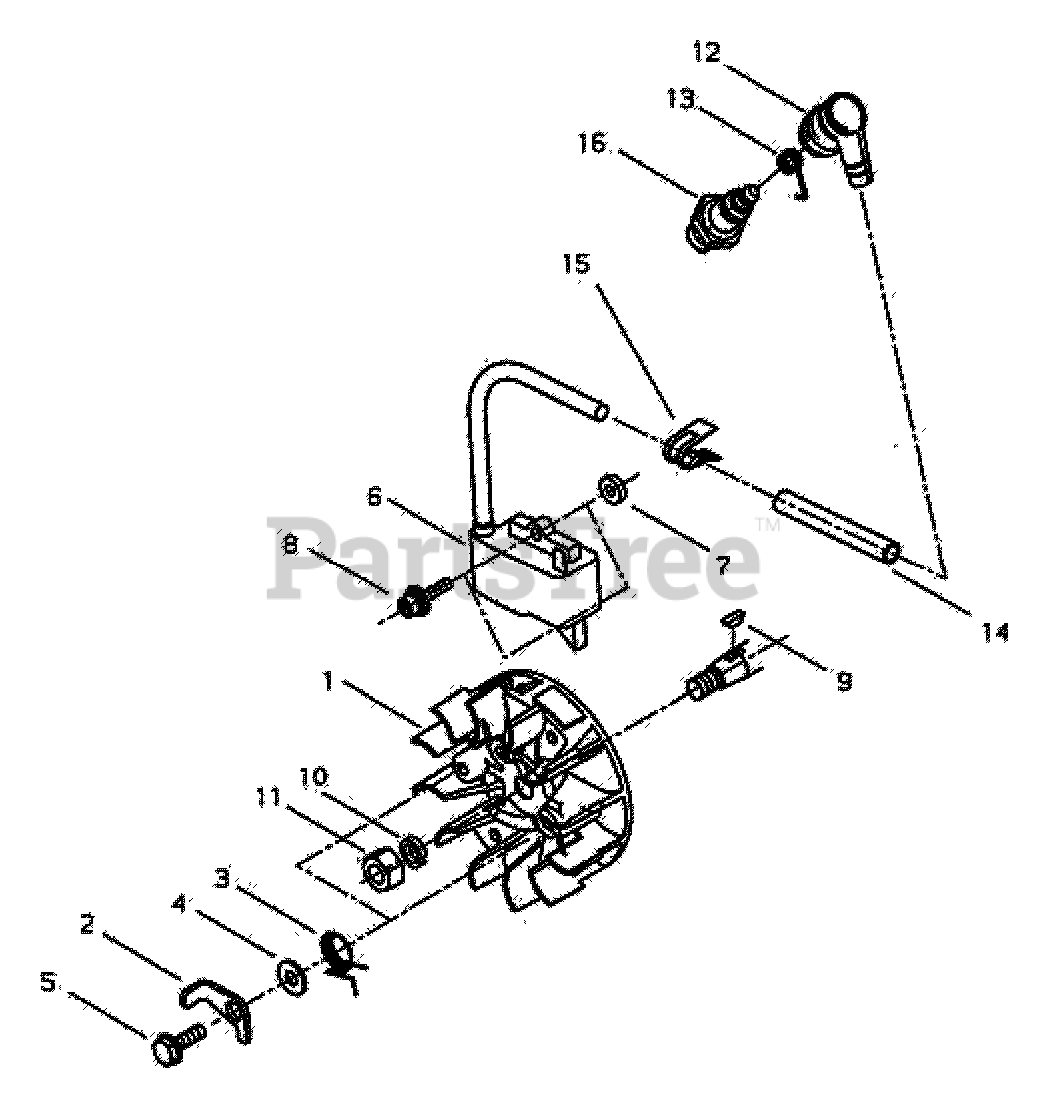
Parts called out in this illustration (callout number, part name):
1	FLYWHEEL
2	PAWL
3	SPRING, TORSION
4	WASHER 6
5	BOLT 6
6	IGNITION COIL ASSY
7	INSULATOR
8	BOLT M4×20
9	KEY, WOODRUFF 3×10
10	WASHER, SPRING 8
11	NUT
12	CAP, SPARK PLUG
13	TERMINAL, SPARK PLUG
14	TUBE, INSULATOR
15	CLIP
16	SPARK PLUG - BPMR7A
